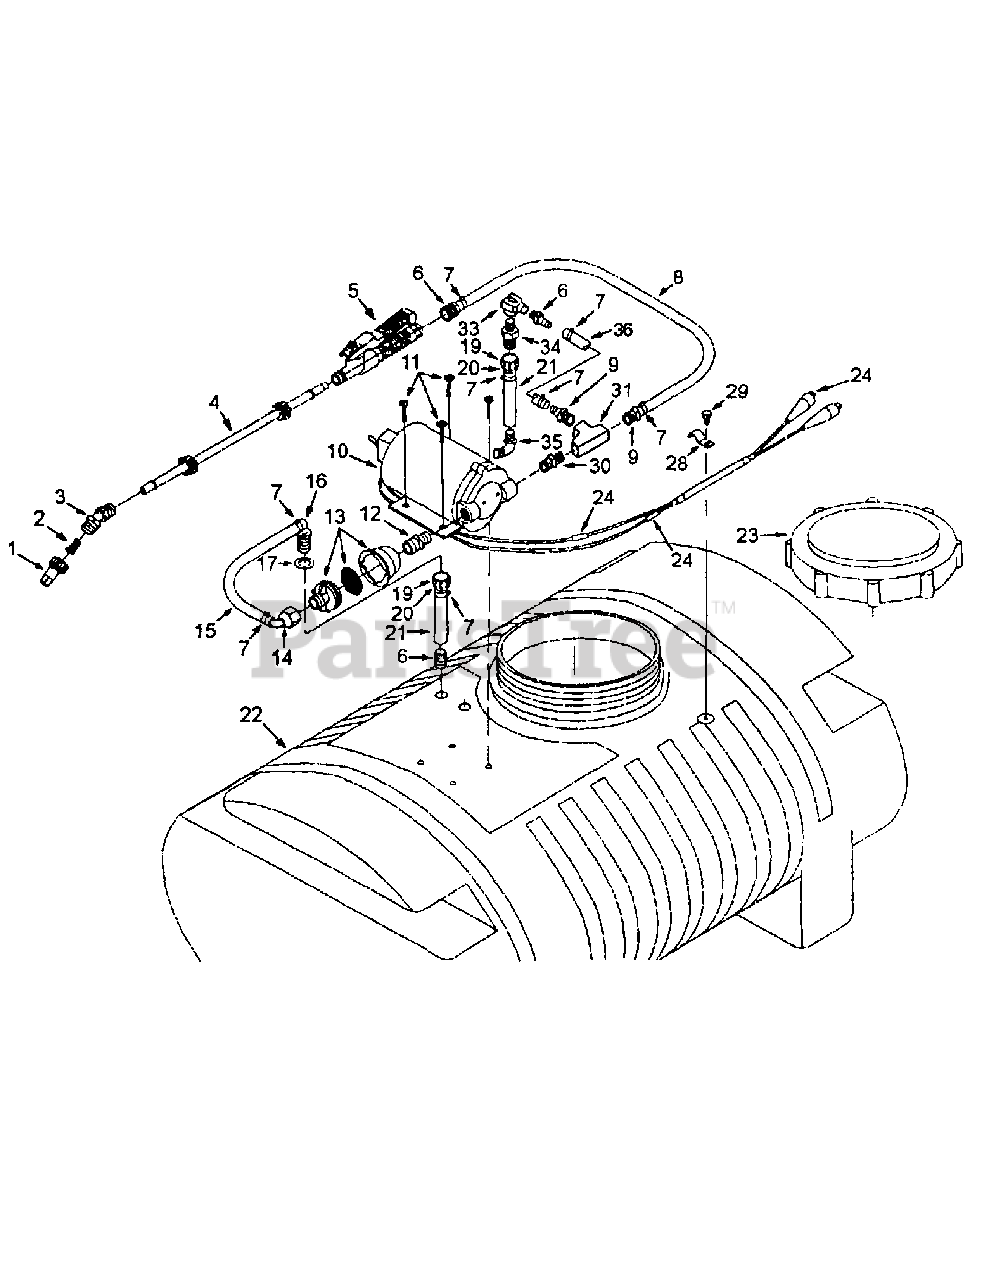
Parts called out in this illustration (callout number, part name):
1	Spray Tip, Adjustable
2	Strainer
3	Adapter, 45°.
4	Extension Wand, 15"
5	Trigger Valve
5	Wand Assembly
6	Hose Barb, 3/8 x 1/4 MPT
7	Hose Clamp
8	3/8 Hose, Reinforced PVC-25 ft.
8	Hose, 1/4" x 25', Flex Coil
9	Hose Barb, 3/8 x 3/8 MPT
10	Diaphragm Pump, Flojet
11	Mach. Screw, # 10-24 x 3/4 Pan Hd.
12	Fitting, Adapter
13	Filter, 30 Mesh S.S. Screen
14	Hose Barb, 3/8 x 90° Swivel Elbow
15	Hose, 3/8" x 18'
16	Hose Barb, 3/8" x 90° Male Elbow
17	Washer, 11/16 Nylon
19	Swivel Nut, Nylon
20	Hose Barb, 3/8 Nylon
21	Hose, 3/8" x 14'
22	Tank, 15 Gallon, Polyethylene
22	Tank, 25 Gallon, Polyethylene
23	Tank Lid
24	Wire Harness
28	Conduit Strap, 1/2
29	Cap Screw, 5/16-18 x 1/2 Hex Hd.
30	Nipple, 3/8 MPT Close
31	Tee, 3/8 FPT Brass
32	Hose Kit
33	Valve, 90°, 1/4 FPT
34	Fitting, Adapter, 1/4 MPT x 11/1 61
35	Elbow, 90°, 1/4 MPT x 3/8 Hose Barb
36	Hose, 3/8" x 5" PVC
